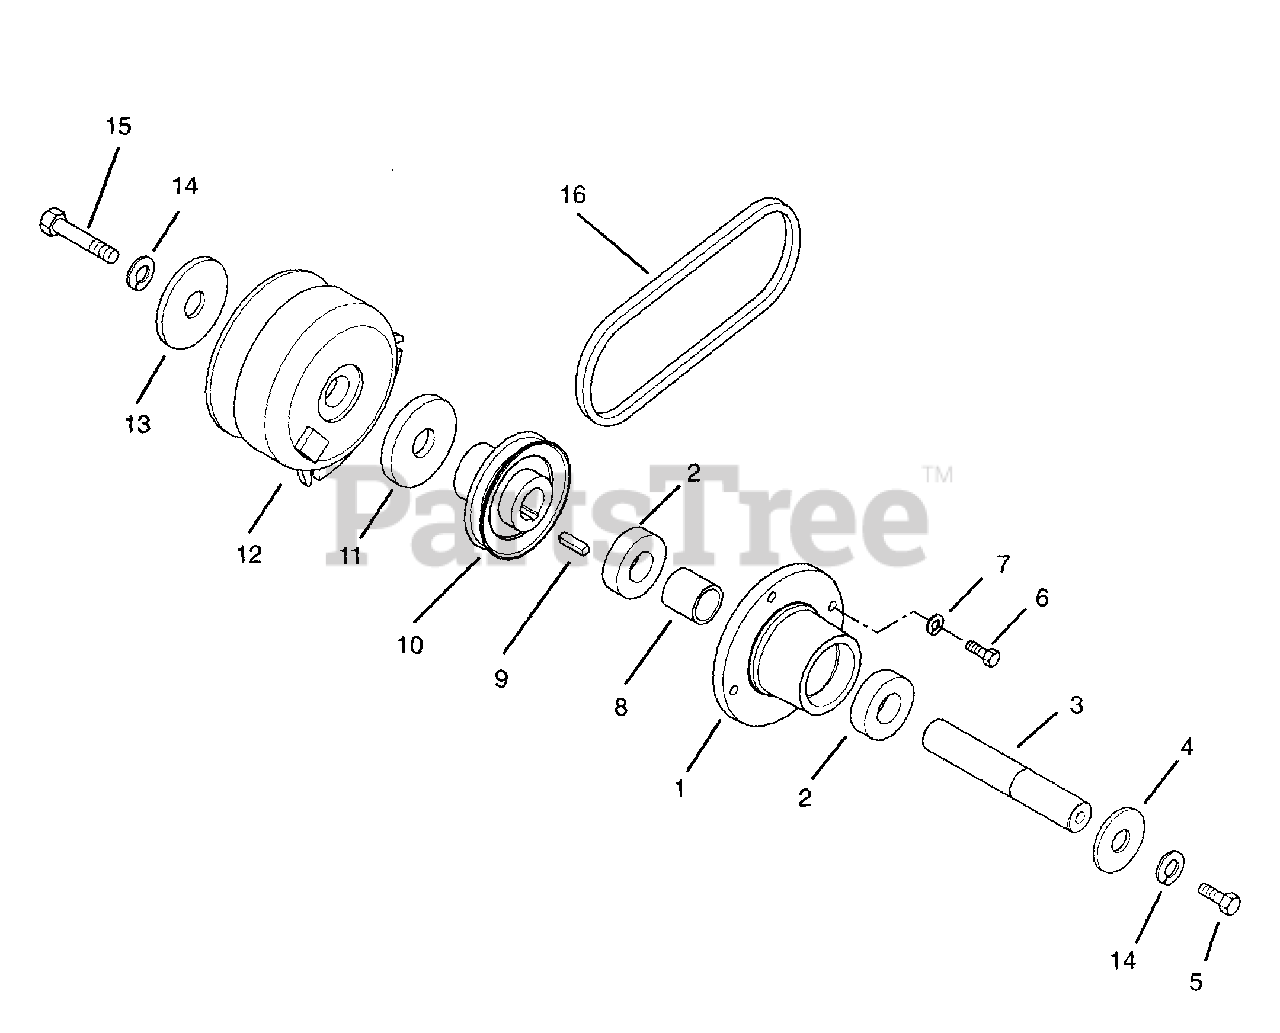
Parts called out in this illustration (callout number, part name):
1	HOUSING, TRANS SPNDL, BLACK
2	BRG-BALL .984X2.04X.59
3	SHAFT, JACK
3	SHAFT 1540/1648
4	WSHR-FL-STL .463X1.375X.250 PL
5	BLT-HEX .44-20X1.00 GR5
6	BLT-HEX .31-18X.75 PL GR5
7	WSHR-LK .313X.078 PL MED
8	SPACER 1.0X1.253X1.26
9	KEY-SQ .25X1.0X.25 SAE 8630
10	SHEAVE, JACKSHAFT
11	SPACER 1.004X1.500X.740
12	ELECTRIC CLUTCH/BRAKE(1.8AMP)
12	CLUTCH, ELECTRIC - WARNER
13	WSHR-SPECIAL .469X2.000X.250
14	WSHR-LK .438X.133 HVY
15	BLT-HEX .44-20X2.50
15	BLT-HEX .44-20X1.50 PL GR5
16	BELT
16	BELT, ENGINE TO JACKSHAFT
